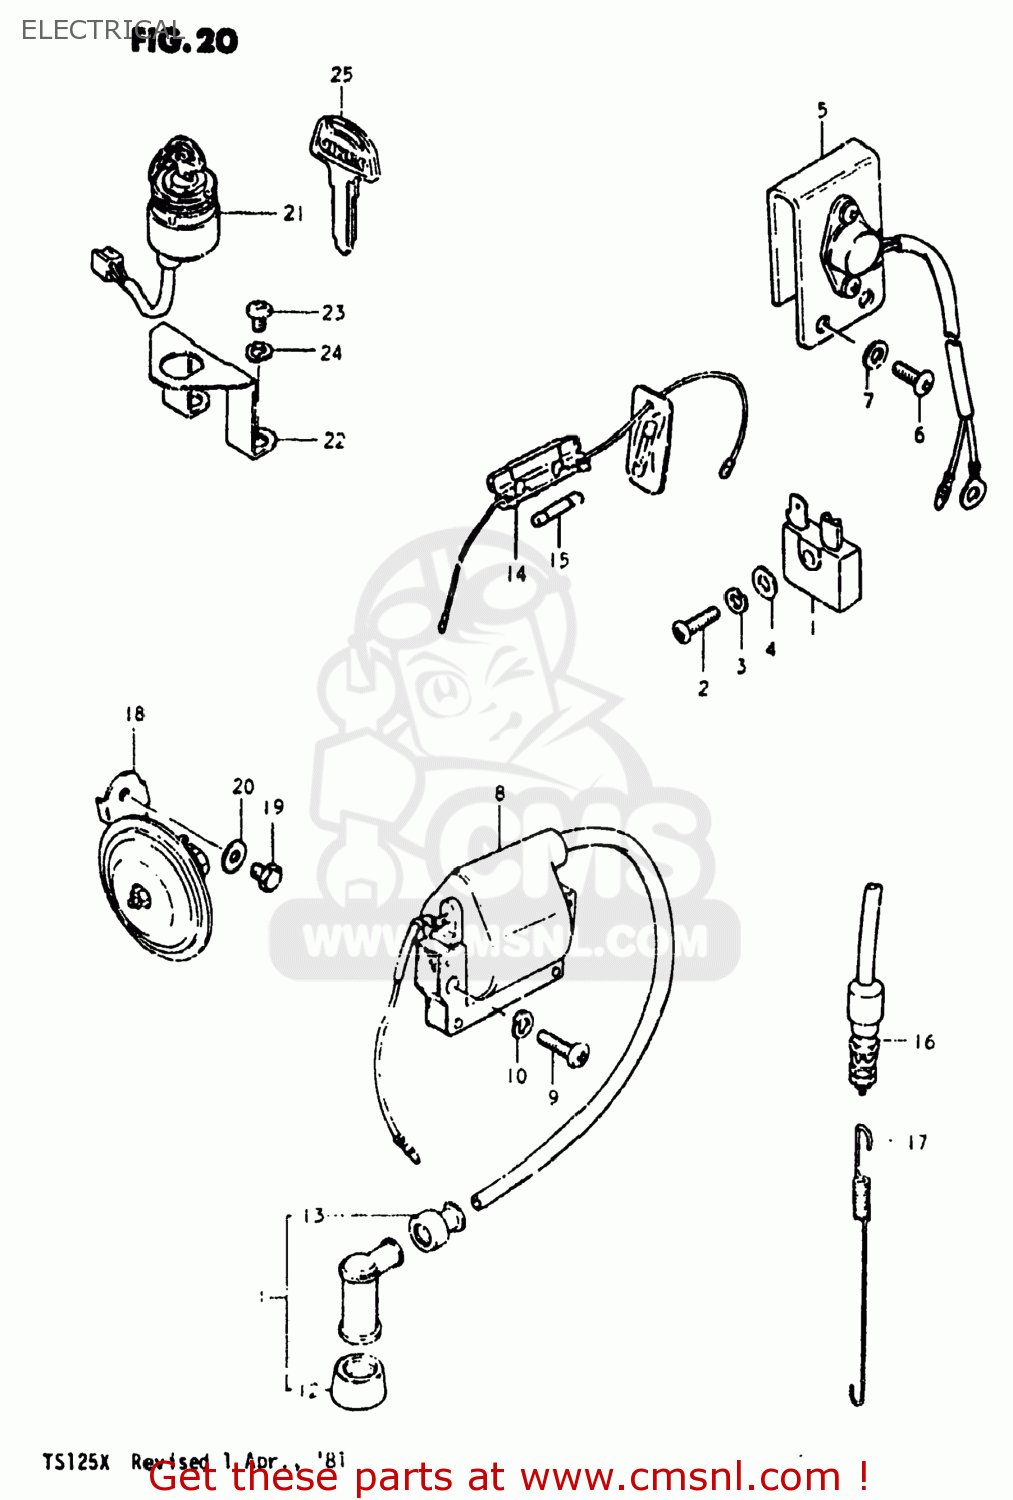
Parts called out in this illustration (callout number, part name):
1	RECTIFIER ASSEMBLY
2	SCREW 5X20
3	LOCK WASHER
4	WASHER
5	REGULATOR ASSEMBLY
6	SCREW 6X12
7	WASHER
8	UNIT & COIL ASSEMBLY,IGNITION
9	SCREW
10	LOCK WASHER
11	CAP,SPARK PLUG
12	SEAL,SPARK PLUG
13	SEAL,SPARK PLU
14	BOX ASSEMBLY,FUSE
15	FUSE(10A)
16	SWITCH ASSEMBLY,STOP LAMP
17	SPRING
18	HORN ASSEMBLY
19	BOLT
20	WASHER
21	SWITCH ASSEMBLY,IGNITION
22	BRACKET,IGNITION SWITCH
23	SCREW
24	LOCK WASHER
25	KEY,BLANK
